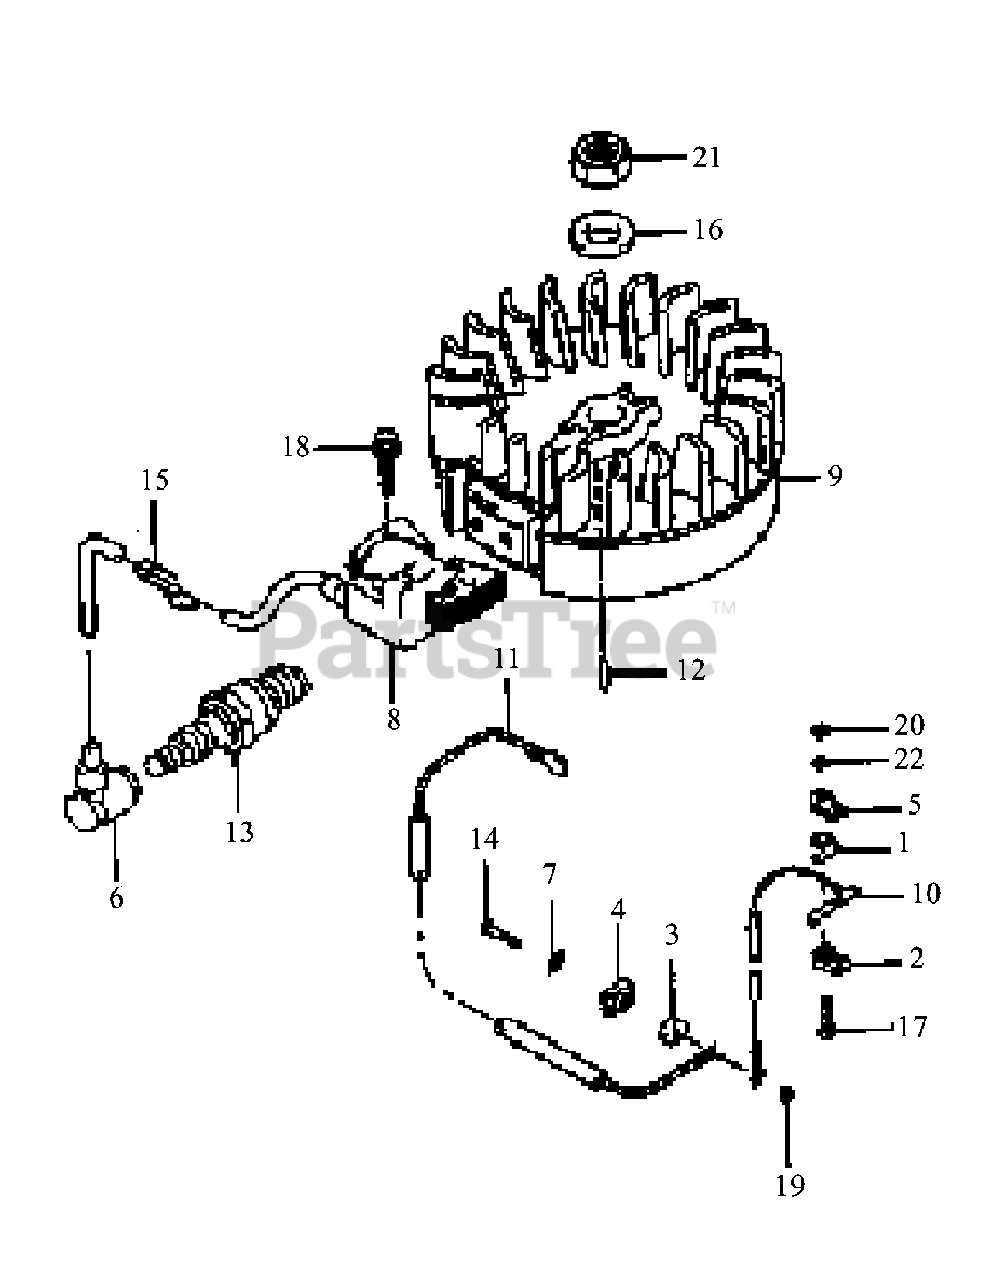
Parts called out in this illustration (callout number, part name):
4	Insulator
6	Cap, Spark Plug
8	Coil, Assembly, Ignition
9	Flywheel, Complete
11	Wire Lead 300mm
13	Plug, Spark
17	Bolt
18	Bolt, Flange
21	Nut, Hex Fine
22	Washer Plain
